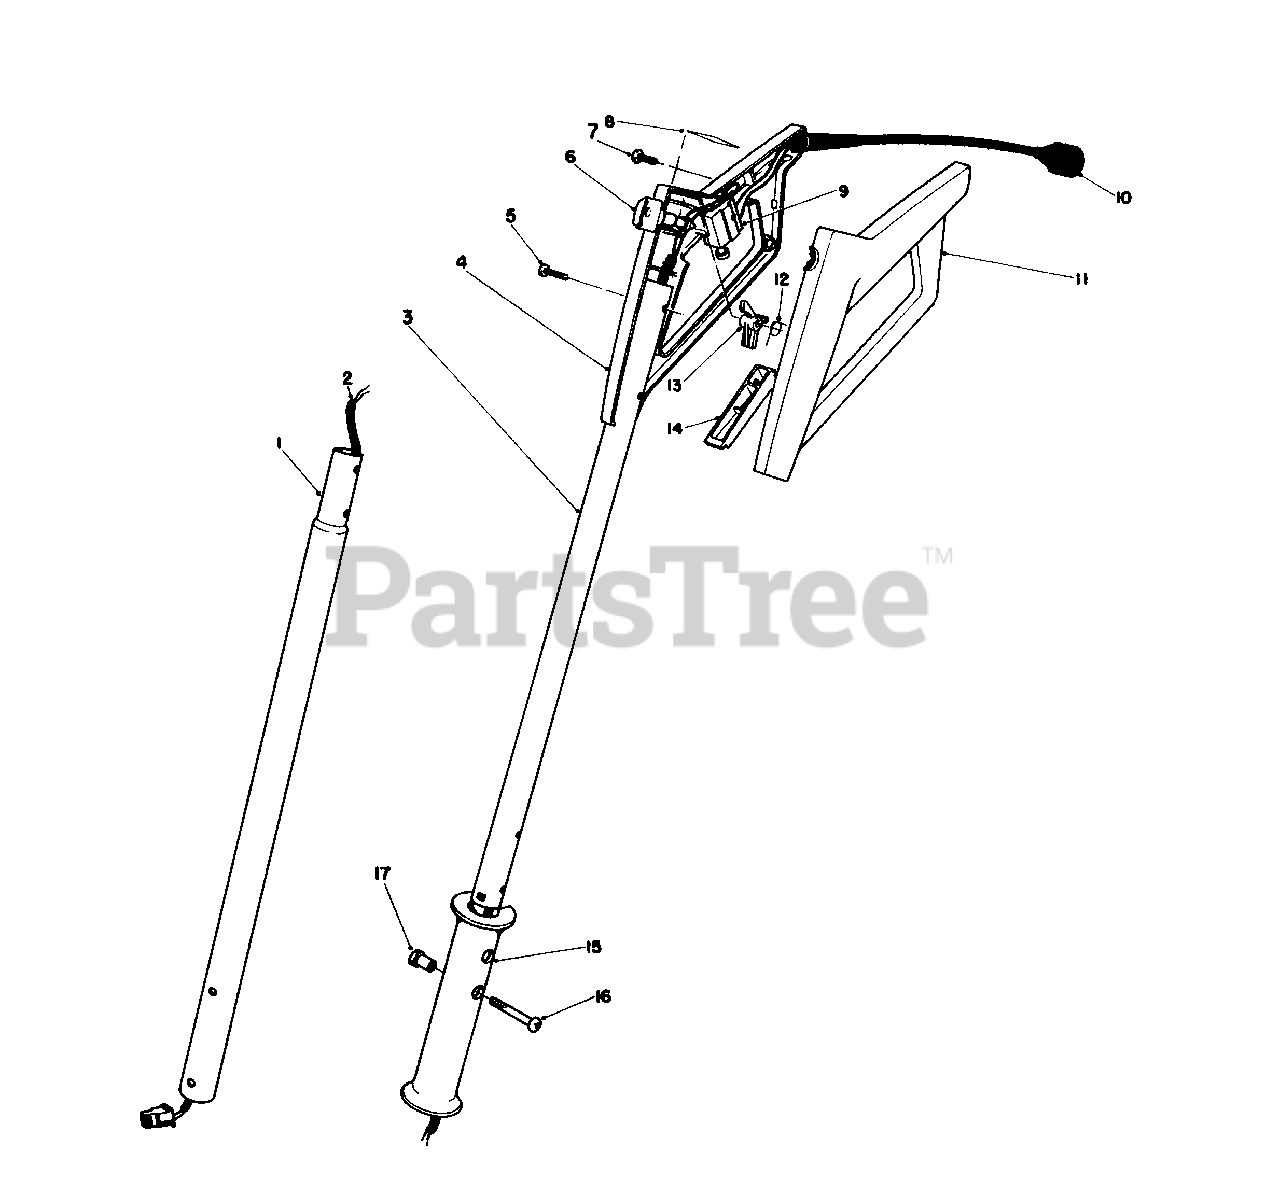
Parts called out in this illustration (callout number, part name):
1	Tube-Lower Handle
2	Wire Harness (Model #38310)
3	Tube-Upper Handle
4	Grip-Control R.H.
5	Screw-Pan Head
7	Screw-Pan Head
8	Decal-Control Grip (Model #38310)
10	Cord-Supply
11	Grip-Control L.H.
14	Switch Bar
15	Grip-Handle
16	Screw-Pan Head Special
17	Nut-Hex Special
